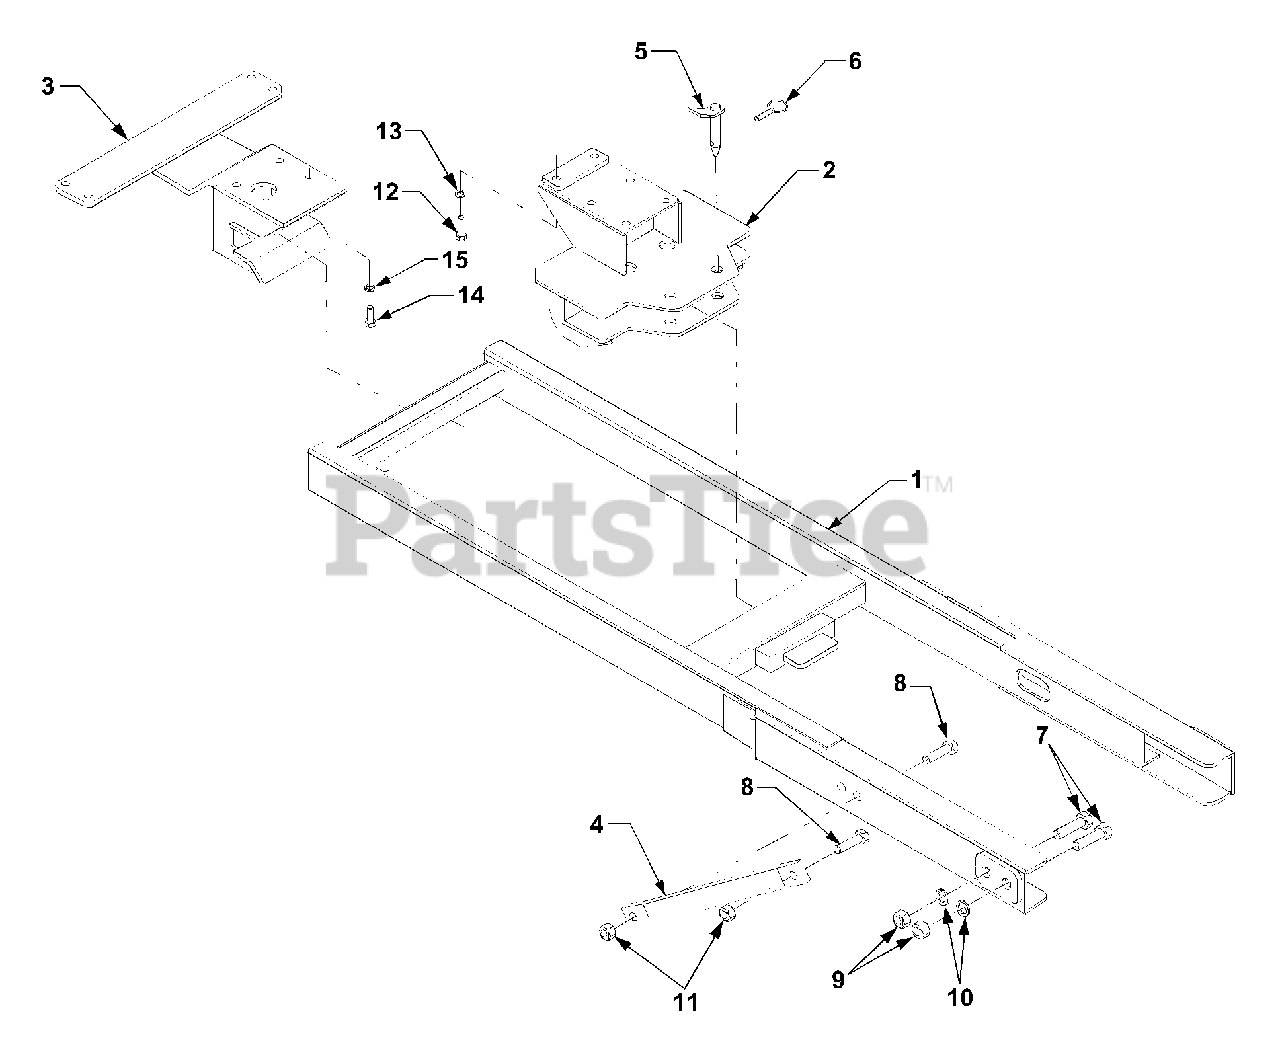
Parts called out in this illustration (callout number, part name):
2	Rear Subframe Mount
3	Front Subframe Mount
5	Retaining Pin
7	Hex Head Screw, M22 x 80
8	Hex Head Screw, M20 x 70
9	Hex Nut, M22
10	Spring Washer
12	Hex Head Screw, M14 x 40
13	Spring Washer
14	Hex Head Screw, M12 x 35
15	Spring Washer
